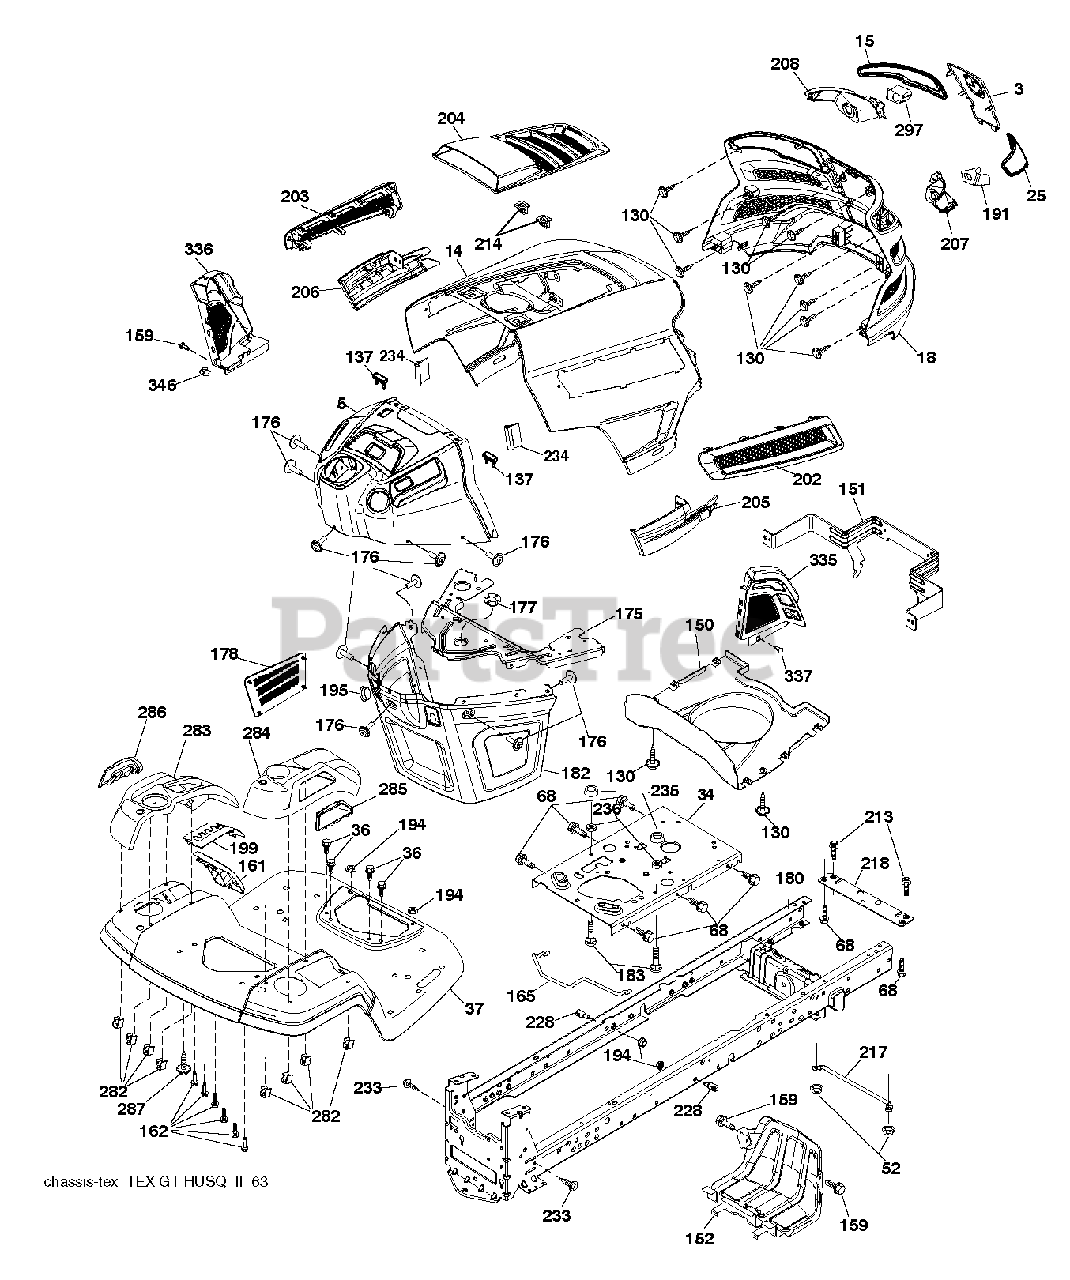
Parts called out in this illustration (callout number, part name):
3	APPLIQUE.SUBASM.GT.HUSQ.II
5	DASH.UPP.GT2.SM.PTO.MCHOKE
14	HOOD.ASM.HUSQVARNA.GT.TEX.ORAN
15	LENS.HEADLIGHT.LH.GTII.2011
18	GRILLE.SUBASM.GT.HUSQ.II
25	LENS.HEADLIGHT.RH.GTII.2011
34	PLATE.ENGINE.WELDED.CHASSIS
36	SCREW 5/16"
37	FENDER.TLT.FS.W/CPH/FW/RSF.668
52	LOCKNUT
68	SCREW LT
130	SCREW.#10 X 0.750.BOS
137	BUMPER DASH
150	AIR.DUCT.GTV.BLACK
151	BRACKET.PIVOT.HOOD.GT.HUSQ.II
152	SHIELD.BROWNING.PNT.GT.V2
159	SCREW, 3/8-16X3/4
161	WINDOW.FUEL.LT.HUSQ.TEX.498
162	SCREW.HI-LO.CONSOLE
165	SUPPORT.TANK.REAR.W/TEX
175	PLATE.CROSSMEMBER.HUSQ
176	SCREW.#10-24X5/8.RN.QU
177	BUSHING, STEERING
178	CARGO.ASM.NET.TXGT.W/C
180	CHASSIS
182	DASH.LOWER.COMMON.12V.ADAPTOR
183	BOLT.5/16-18X1-1/4 FULL THD
191	INSERT.REFLECTIVE.RH.HUSQ.GTII
194	NUT LOCK HEX FLANGE 5/16-18
195	PLUG.HOLE.DASH.LOWER.12V.BLK
199	PLATE.DECK.LIFT.HUSQ.LT
202	VENT.SIDE.RH.GT.HUSQ.II.
203	VENT.SIDE.LH.GT.HUSQ.II.498
204	VENT.TOP.HUSQ.GT2
205	SIDE.TRIM.RH.GT.HUSQ.II
206	SIDE.TRIM.LH.GT.HUSQ.II.GRAY
207	BEZEL LIGHT.RH.GT.II.MYLAR
208	BEZEL LIGHT.LH.GT.II.MYLAR
213	BOLT
214	CLIP.RETAINER.TINNER.
217	ROD.PIVOT.HOOD
218	X-PIECE.HOOD.STOP.NON/
228	STUD.FASTNER.W/ANTI-ROTATE
233	BOLT.SHOULDER
234	BUMPER.HOOD.TEX.HUSQVARNA
235	SPACER FENDER
236	NUT.CENTERLOCK.5/16-
282	CLIP.RETAINER.CONSOLE.LT.HUSQ
283	CONSOLE.DECK.LIFT.R.SDFL.HUSQ
284	CONCOLE.CNTRL.PDL.HUSQ.LT.498
285	CONSOLE INSERT RH
286	CONSOLE.INSRT.LH.HUSQ.LT.BLACK
287	SCREW 1/4X20
297	INSERT.REFLECTIVE.LH.HUSQ.GTII
335	COVER.RH.CLOSE.OUT.BLACK
336	COVER-LH.LOWER.DASH.GT2.BLACK
337	CLIP.XMAS.TREE.ITW.2622-00
346	CLIP,INSULATOR
